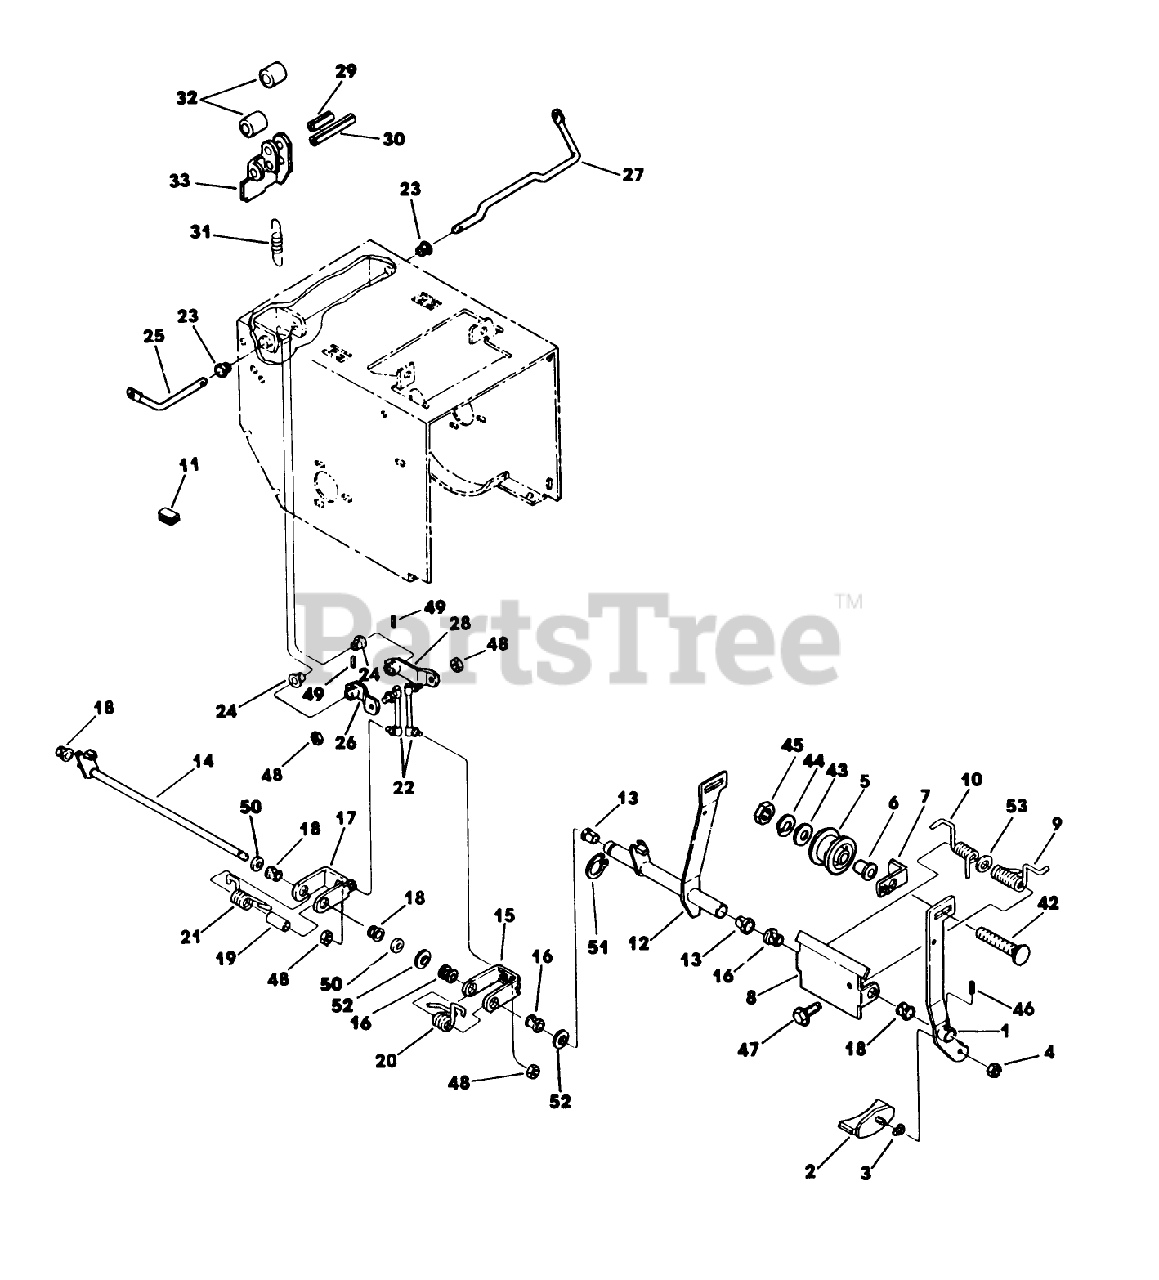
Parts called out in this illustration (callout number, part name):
27	TRACTION CONTROL ROD
33	INTERLOCK LEVER
47	SCREW-HWH
50	WASHER - SHIM
51	RING-RETAINING
